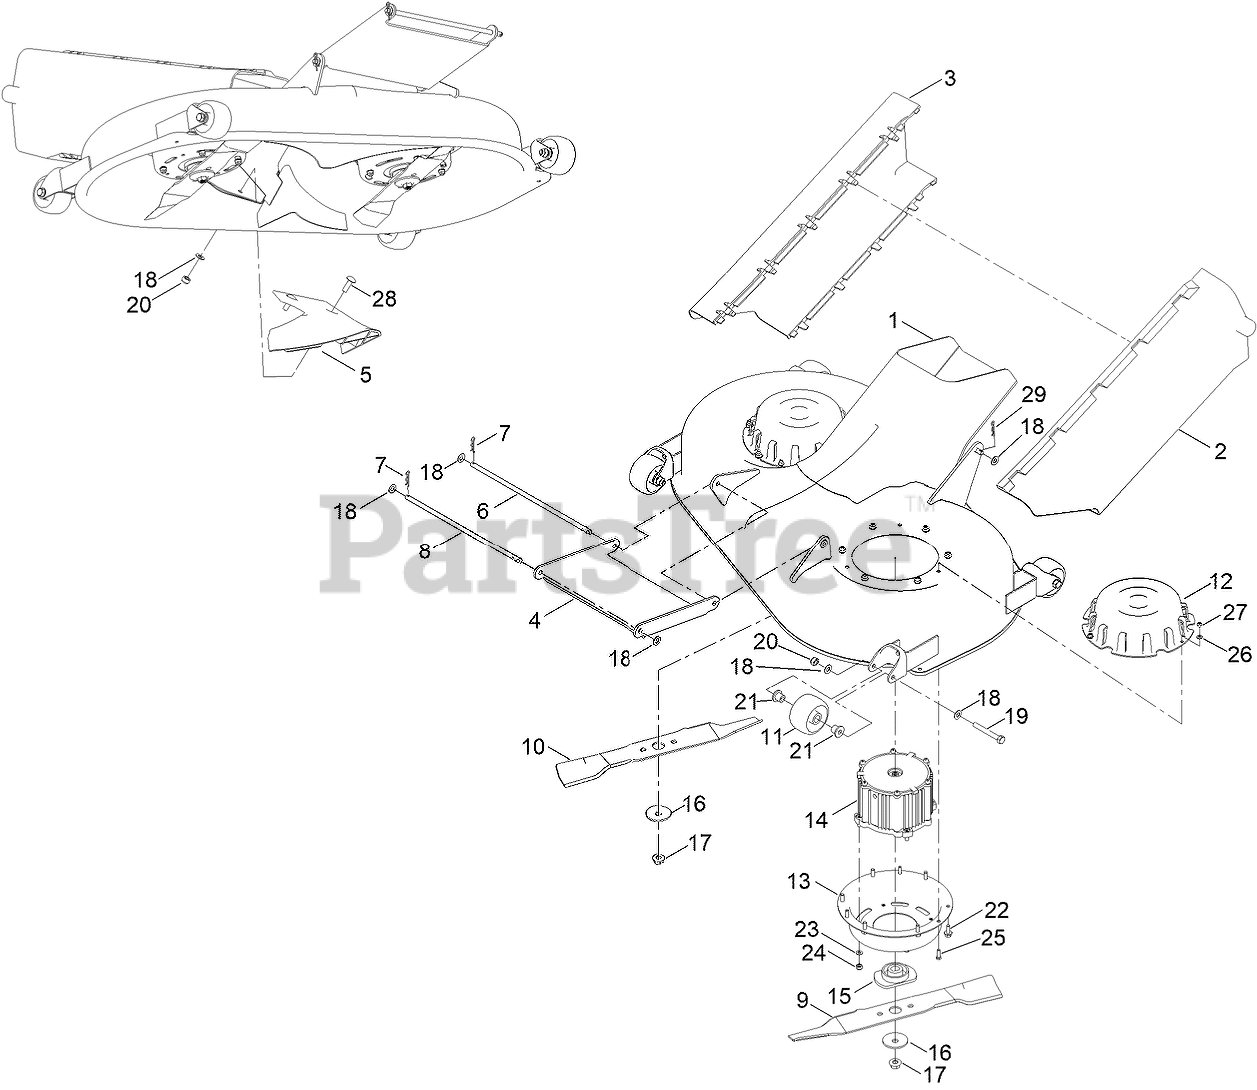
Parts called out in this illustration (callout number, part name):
1	WELDED DECK (DIRECT COLLECT)
2	DECK CHUTE (LH)
3	DECK CHUTE (RH)
4	DECK LIFT
5	BAFFLE, DECK
6	DECK LIFT ROD (LONG)
7	R CLIP
8	DECK LIFT ROD (SHORT)
9	BLADE, DIRECT COLLECT (LH)
10	BLADE, DIRECT COLLECT (RH)
11	WHEEL, DECK
12	TOP COVER, DECK MOTOR
13	BOTTOM COVER, DECK MOTOR
14	MOTOR, DECK
15	HUB, BLADE MOTOR
16	WASHER, BLADE
17	NUT, BLADE
18	WASHER-PLAIN
20	NUT-HEX, NI
21	INSERT, DECK WHEEL
22	SCREW-HHF
23	WASHER-PLAIN
24	NUT-NYLOC
25	SCREW-HH
26	WASHER
27	NUT-NYLOC
28	BOLT-COACH
29	R CLIP
